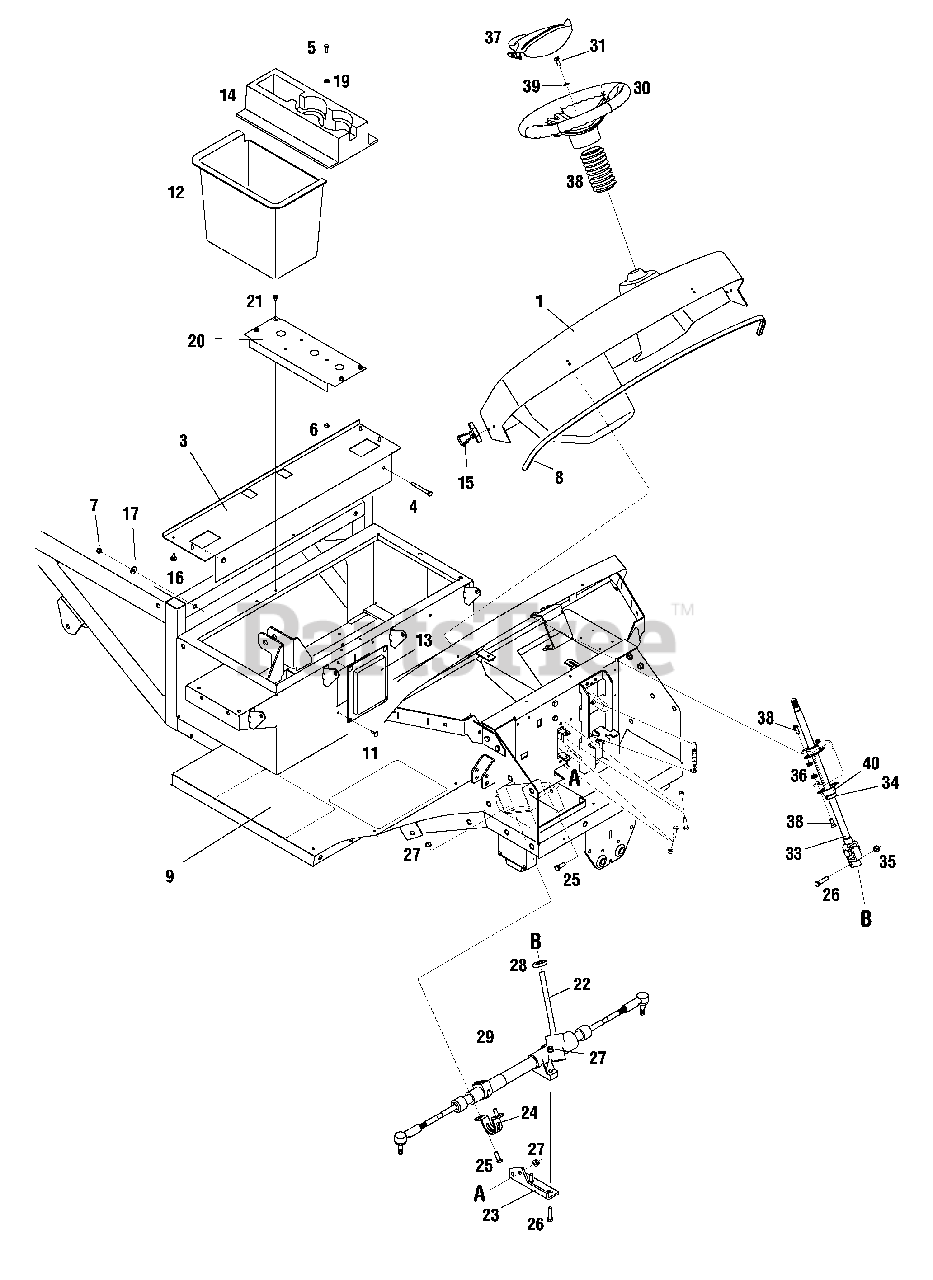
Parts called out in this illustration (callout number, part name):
1	Dash Assembly
2	Hood Mounting Plate
5	Hex Screw, 1/4-20 x .75, Gr5
6	Hex Lock Nut, Nylon, 1/4-20
7	Hex Lock Nut, Nylon, 5/16-18
8	Trim, Bulb Seal, 1/4
9	Foot Pad, Abrasive
10	Rivet, Pop, .187
11	Rivet, Pop, .188
12	Container, Bulkhead
13	Panel, Shift Cover
14	Console, Cup Holder
15	Handle, Latch
16	Bumper, Rubber
17	Washer, Flat, .349 x .879 x .063
18	Washer, Flat, .194 x .62 x .063
19	Washer, Flat, .25 x .630 x .0515
22	Gear Assembly, Steering
25	Hex Screw, 3/8-16, 1.00, Gr5
26	Hex Screw, 3/8-16, 1.50, Gr5
27	Nut, Flange Lock, 3/8-16
28	Grommet, Steering Shaft
29	Bushing, Rubber
30	Wheel, Steering
31	Hex Screw, 5/16-18, .75, Gr5, Patch
32	Hex Screw, 5/16-18, .75, Gr5
33	Shaft, Steering, 5/8 Spline
34	Collar, .75
35	Nut, Hex Lock Nylon, 3/8-16
36	Nut, Flange Lock, 5/16-18
37	Cover, Steering Wheel
38	Bellow, Steering, 4.75 Lg
39	Washer, Flat, .344 x .688 x .065
40	Bearing, Flange, .75 ID, Self-Aligning
